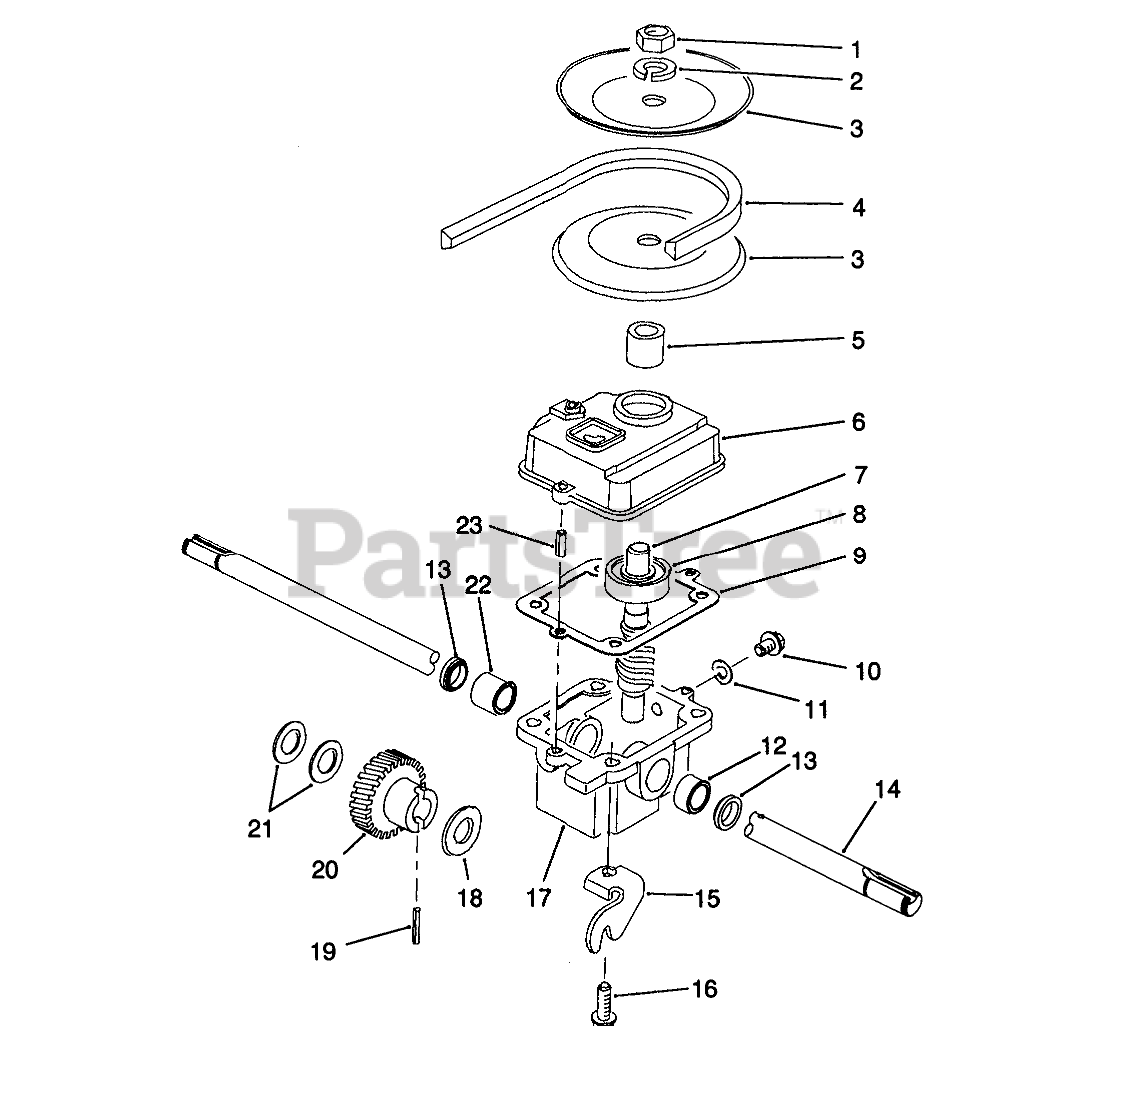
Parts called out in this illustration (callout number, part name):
1	NUT-JAM
2	WASHER-LOCK
3	PULLEY-DRIVEN HALF
4	V-BELT
5	SPACER - PULLEY
6	GEAR CASE COVER
7	SHAFT - WORM
8	BEARING
9	GASKET
10	NYLON SCREW
11	FILL PLUG GASKET
12	BUSHING
13	SEAL-OIL
14	OUTPUT SHAFT
15	TRACTION BRACKET
16	SCREW-HWHTF
17	GEAR CASE
18	THRUST WASHER
19	PIN-SPRING
20	GEAR - HELICAL
21	WASHER-PLAIN
22	BUSHING
23	3/16 X 1/2 ROLL PIN
